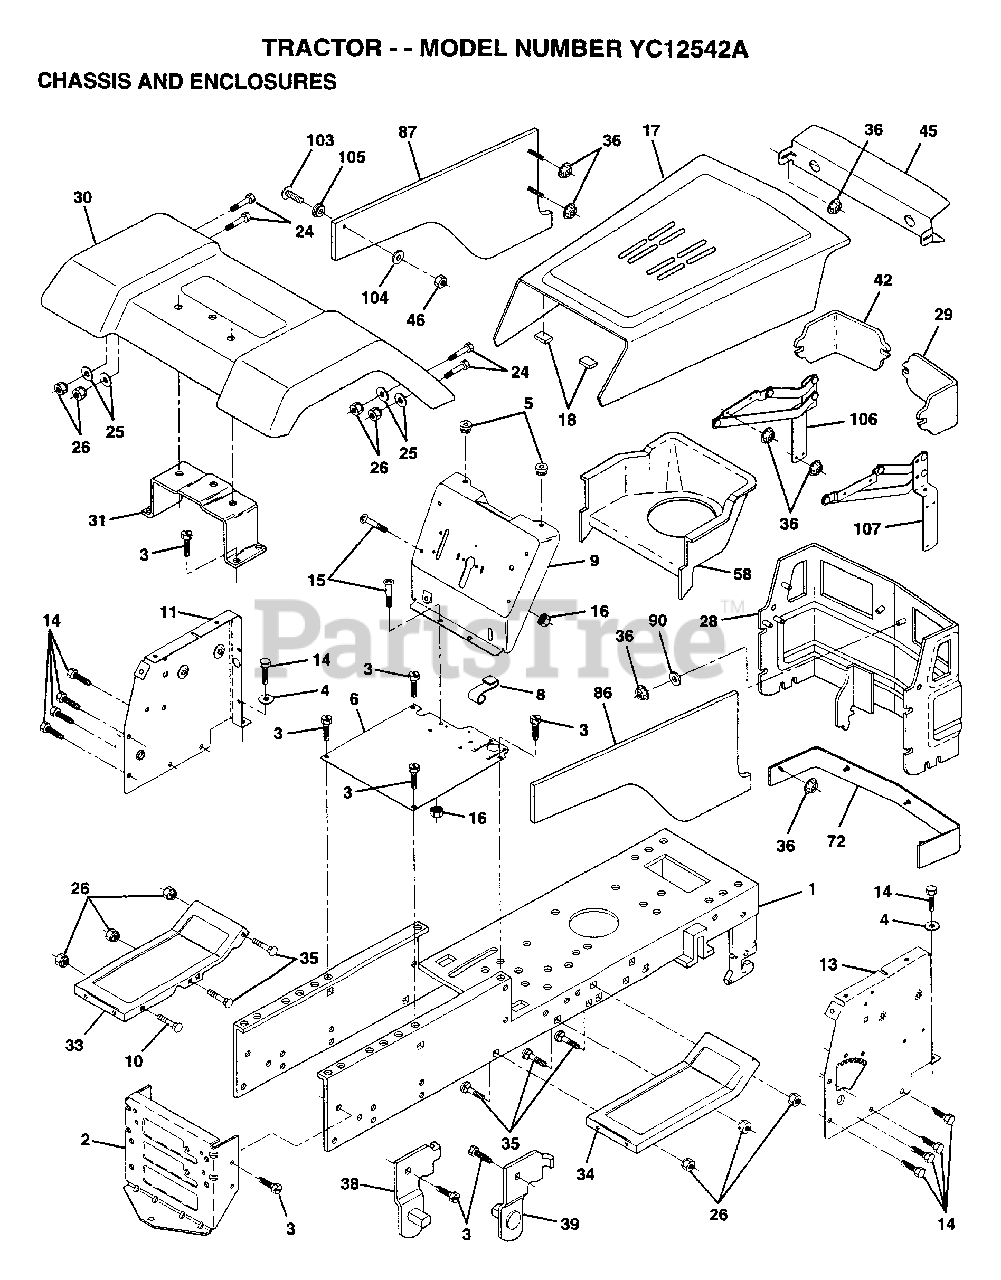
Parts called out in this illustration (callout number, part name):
1	CHASSIS.WLD.11GA
3	SCREW
4	WASHER
8	"CLIP,INSULATOR"
9	DASH.SLKSC.LT.1PC
11	DASH PANEL LH
14	SCREW LT
15	SCREW
24	BOLT
25	WASHER
26	NUT
31	BRKT FENDER
33	FOOTREST.LH.LT/GT
34	FOOTREST.RH.LT/GT
35	BOLT
36	PAL NUT LT
38	BRACKET ASM LH
39	BRACKET ASM RH
46	RETAINER
58	"DUCT, INTAKE T"
72	STRAP ASM GRILL
86	SIDE PANEL ASM RH
87	SIDE PANEL ASM LH
90	WASHER PM
103	"SCREW,SPECIAL"
105	"GROMMET,PLASTIC"
106	"HINGE,HOOD,LH T"
107	"HINGE,HOOD,RH T"
